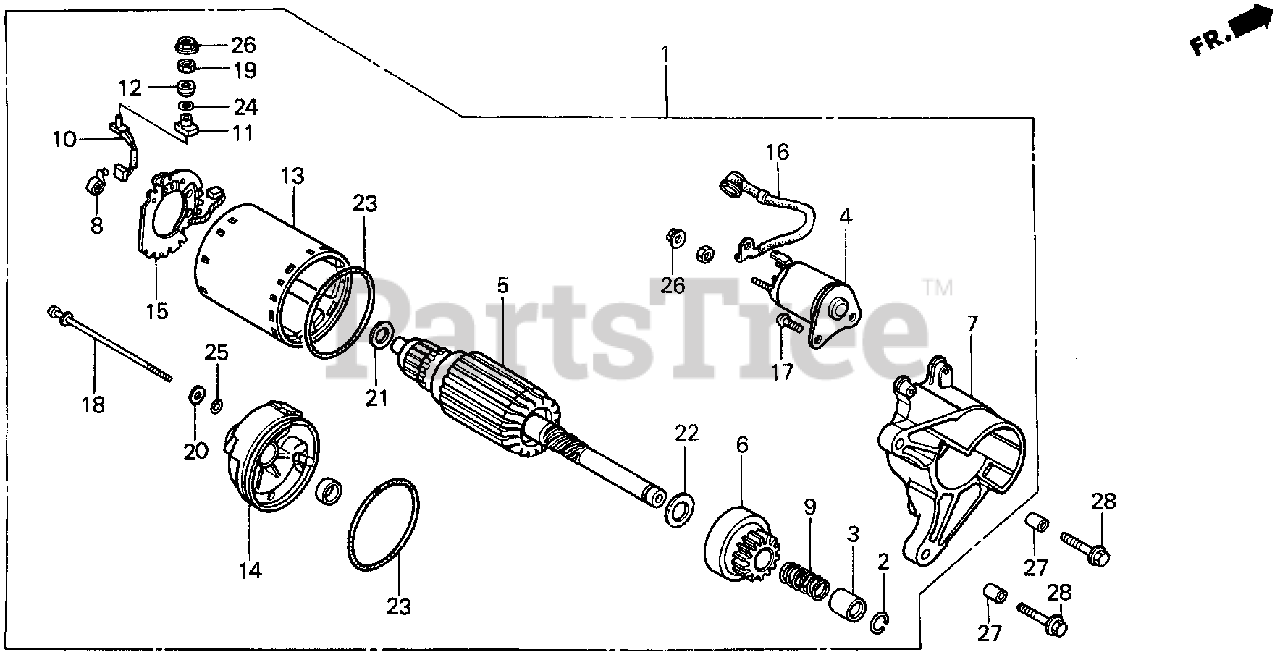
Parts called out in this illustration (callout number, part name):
1	MOTOR ASSY., STARTER
2	RING, SNAP
3	COLLAR, CLUTCH
4	CONTACTOR ASSY.
6	CLUTCH, OVERRUNNING
7	HOUSING, DRIVE SIDE
8	SPRING, BRUSH
11	BUSHING, INSULATION
12	BUSHING, INSULATION
14	FRAME, STARTER END
15	PLATE, BRUSH HOLDER
16	WIRE, WATER COVER
17	BOLT
18	BOLT, THROUGH (NOT AVAILABLE)
18	BOLT, THROUGH
20	WASHER, STEEL PLATE
21	WASHER
26	NUT
26	NUT-WASHER (6MM)
27	PIN A, DOWEL (10X16)
28	BOLT, FLANGE (8X35)
